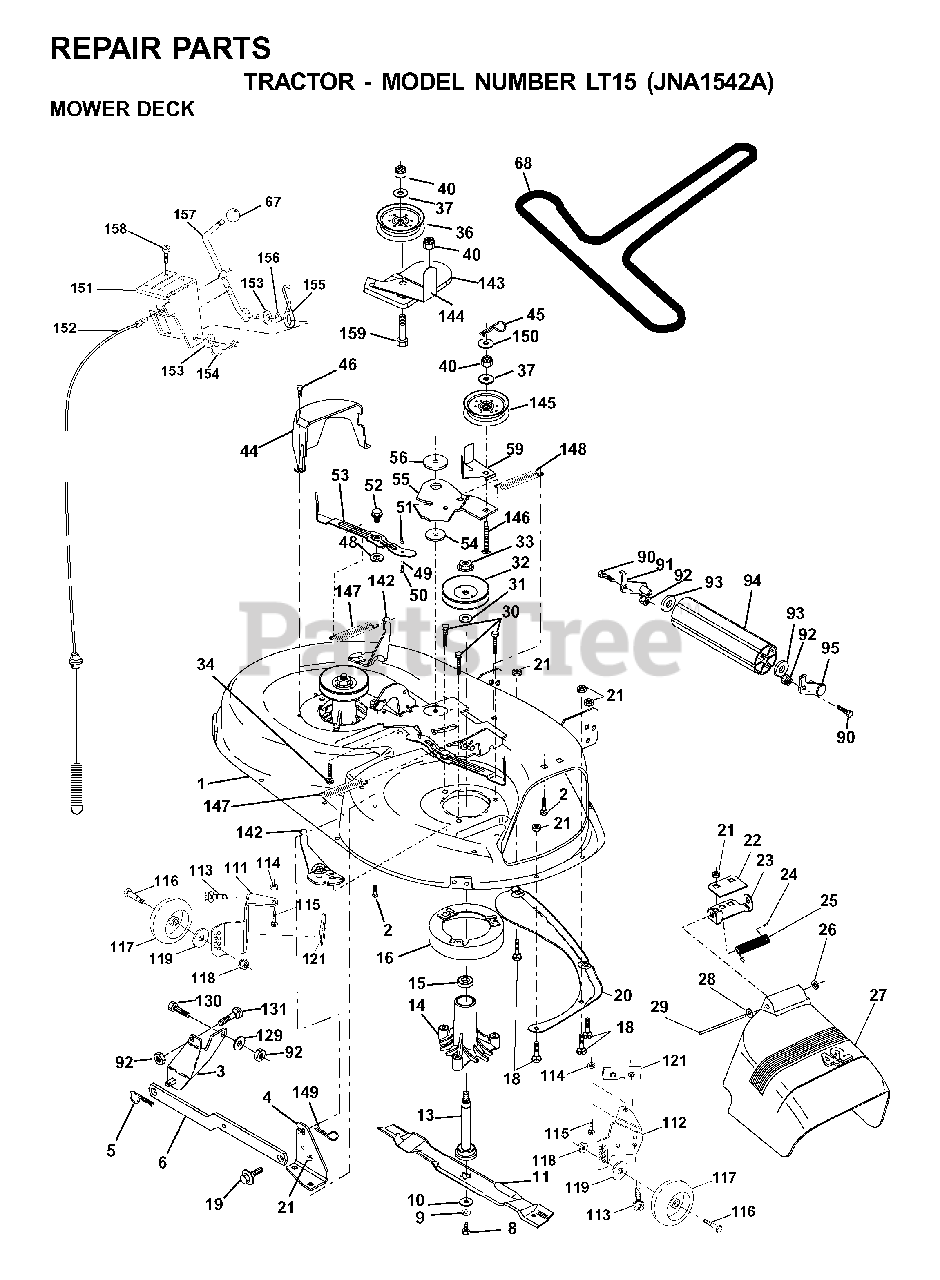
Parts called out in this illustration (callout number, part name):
1	42" DECK KIT
2	BOLT
3	BRKT ASM SWAY BAR
4	BRACKET SWAY BAR 42" DECK
5	RETAINER-SPRNG RB
6	REAR SUSP ARM
8	BLADE BOLT
9	LOCKWASHER
10	WASHER.BLADE
11	BLADE 42"
13	SHAFT ASM VENT
14	HSG MANDREL
16	STRIPPER
18	BOLT
19	BOLT SHD 5/16-18
20	BAFFLE.VORTEX
21	LOCKNUT
22	STIFFENER BRACKET
23	DEFLECTOR BRACKET
24	CAP-SLEEVE LT
25	SPRING TORSION
26	NUT PUSH M
27	SHIELD DEFLECTOR
28	WASHER
29	ROD.HINGE
30	SCREW THDROL ROLLING WASHER HD
31	WASHER
32	PULLEY/MANDREL
33	NUT
34	BOLT
36	FLAT IDLER PULLEY
40	LOCKNUT
44	GUARD MANDREL LH BLACK
45	RETAINER M
46	SCREW.1/4-20X5/8
49	ROLLER ASM CAM FOLLOWER
50	BOLT
53	ARM
54	HARDENED WASHER
55	ARM IDLER 42" MOWER LT/YT
56	SPACER.RETAINER.MOWER
59	GUARD, BELT
67	KNOB T (3/8 HOLE)
68	BELT V SECONDARY
90	BOLT
91	BRACKET LH (A)
92	NUT
94	NOSE ROLLER
95	BRACKET RH (B)
111	BRACKET WHEEL GAUGE LH 42" DK
112	BRACKET WHEEL GAUGE RH 42" DK
114	NUT
115	BOLT
117	WHEEL.GAUGE.STANDARD
118	LOCKNUT
119	WASHER
121	BRACKET.EXTRD.GWL
129	WASHER
131	BOLT D
142	ARM SPRING BRAKE MOWER
143	BRACKET, ARM IDLER
144	KEEPER.BELT.42".CLUTCH.CABLE
145	PULLEY
146	BOLT, CARRIAGE IDLER BLACK
147	SPRING EXTENSION
148	IDLER RETURN SPRING
149	SPRING.RETAINER.YELLOW.ZINC
150	WASHER PM
151	BRACKET, CLUTCH CABLE
152	CLUTCH CABLE 42"
153	WASHER FLAT 3/8"
154	SPRING RETAINER
155	SPRING RETENTION LEVER
156	SPACER CLUTCH CABLE
157	ROD CLUTCH CABLE 3/8"
158	SCREW LT
159	BOLT
532134149	BLADE.42".MULCH
